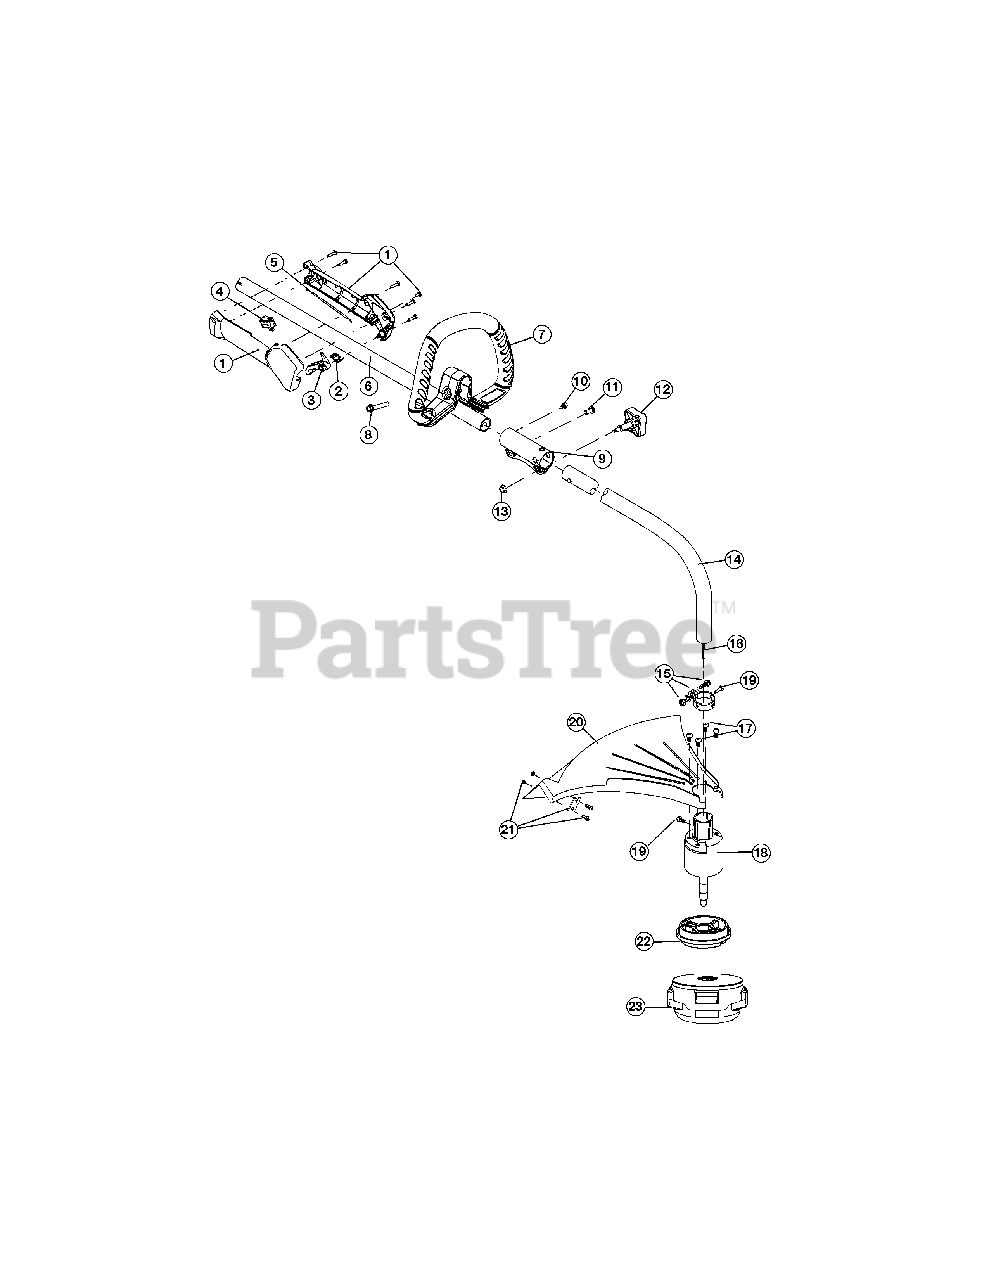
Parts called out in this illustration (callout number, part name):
1	Throttle Housing Assembly
2	Throttle Trigger Spring
3	Throttle Trigger
5	Throttle Cable Assembly
6	Upper Drive Shaft Housing Assembly
7	D-Handle Assembly
9	Split boom Coupler
12	Adjustment Knob
13	Knob Retaining Nut
14	Lower Drive Shaft Housing Assembly
15	Lower Clamp Assembly
16	Lower Flexible Drive Shaft
17	Shield Mounting Screw
18	Bushing Housing Assembly
19	Anti-Rotation Screw
20	Shield Assembly
21	Blade Assembly
23	Spool Assembly
